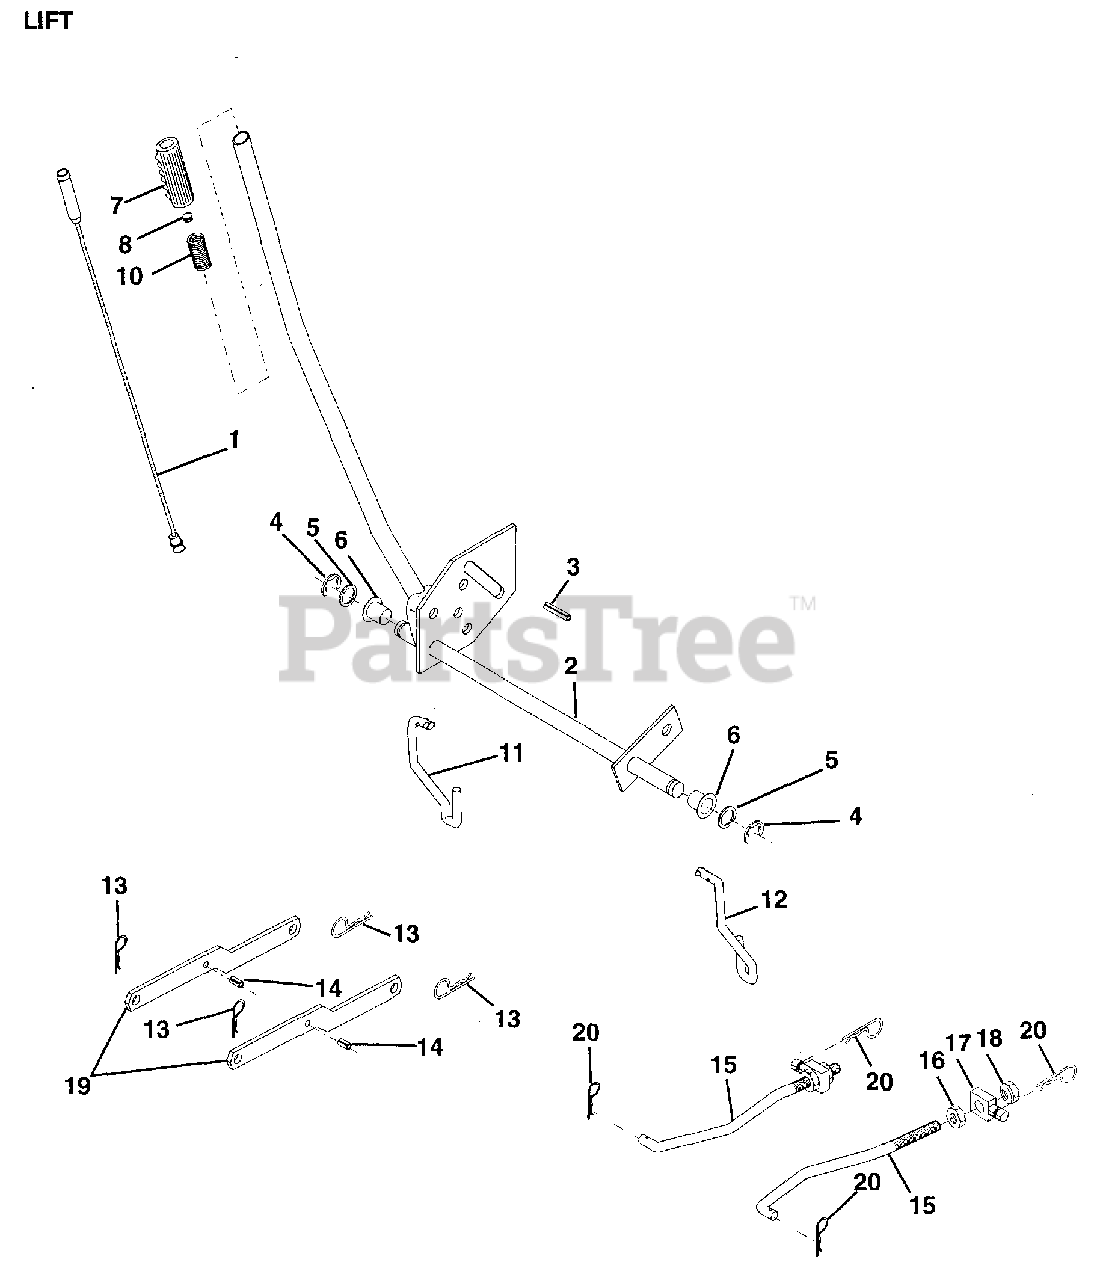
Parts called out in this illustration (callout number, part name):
1	WIRE ASM
2	SHAFT.ASM.LIFT LH
3	PIN GROOVE
5	WASHER
6	NYLON BEARING
7	GRIP
11	LINK LIFT LH
12	LIFT LINK RH
14	"PIN,SPRING"
15	LINK.FRONT
16	NUT
17	TRUNION
18	NUT.LK.W/WSH.1/2.
20	RETAINER.SPRING
